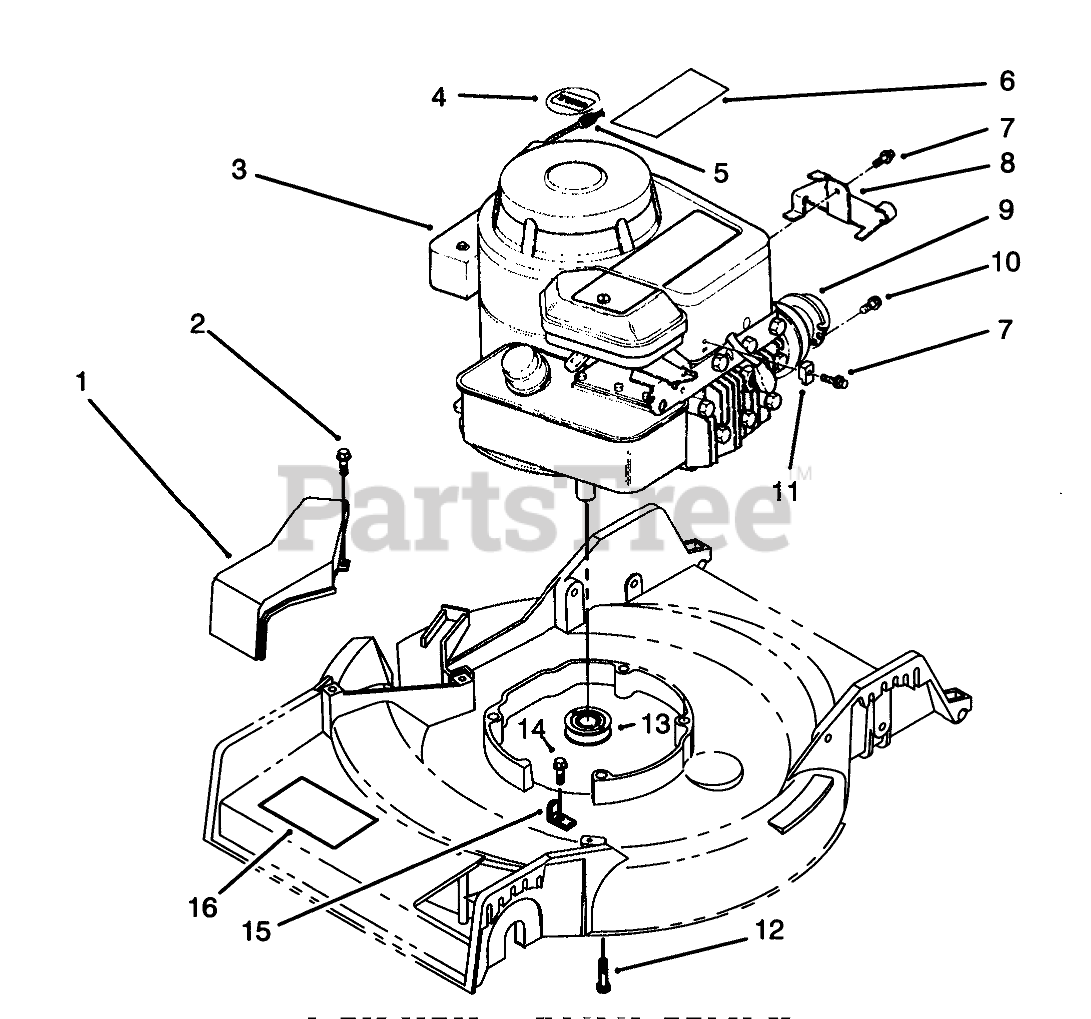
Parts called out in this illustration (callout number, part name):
1	BELT COVER 21" S D
2	SCREW-HWH
4	Decal-Toro
5	STOP-ROPE
6	Decal-Engine
7	CLAMP SCREW F/W ENGINE
8	CABLE BRACKET
9	MUFFLER DEFLECTOR F/W
10	SCREW W/ENGINE
11	CASING CLAMP F/W ENGINE
12	THD FORM SCREW
13	Pulley
14	SCREW-HWHTF
15	BELT GUIDE
16	DECAL
